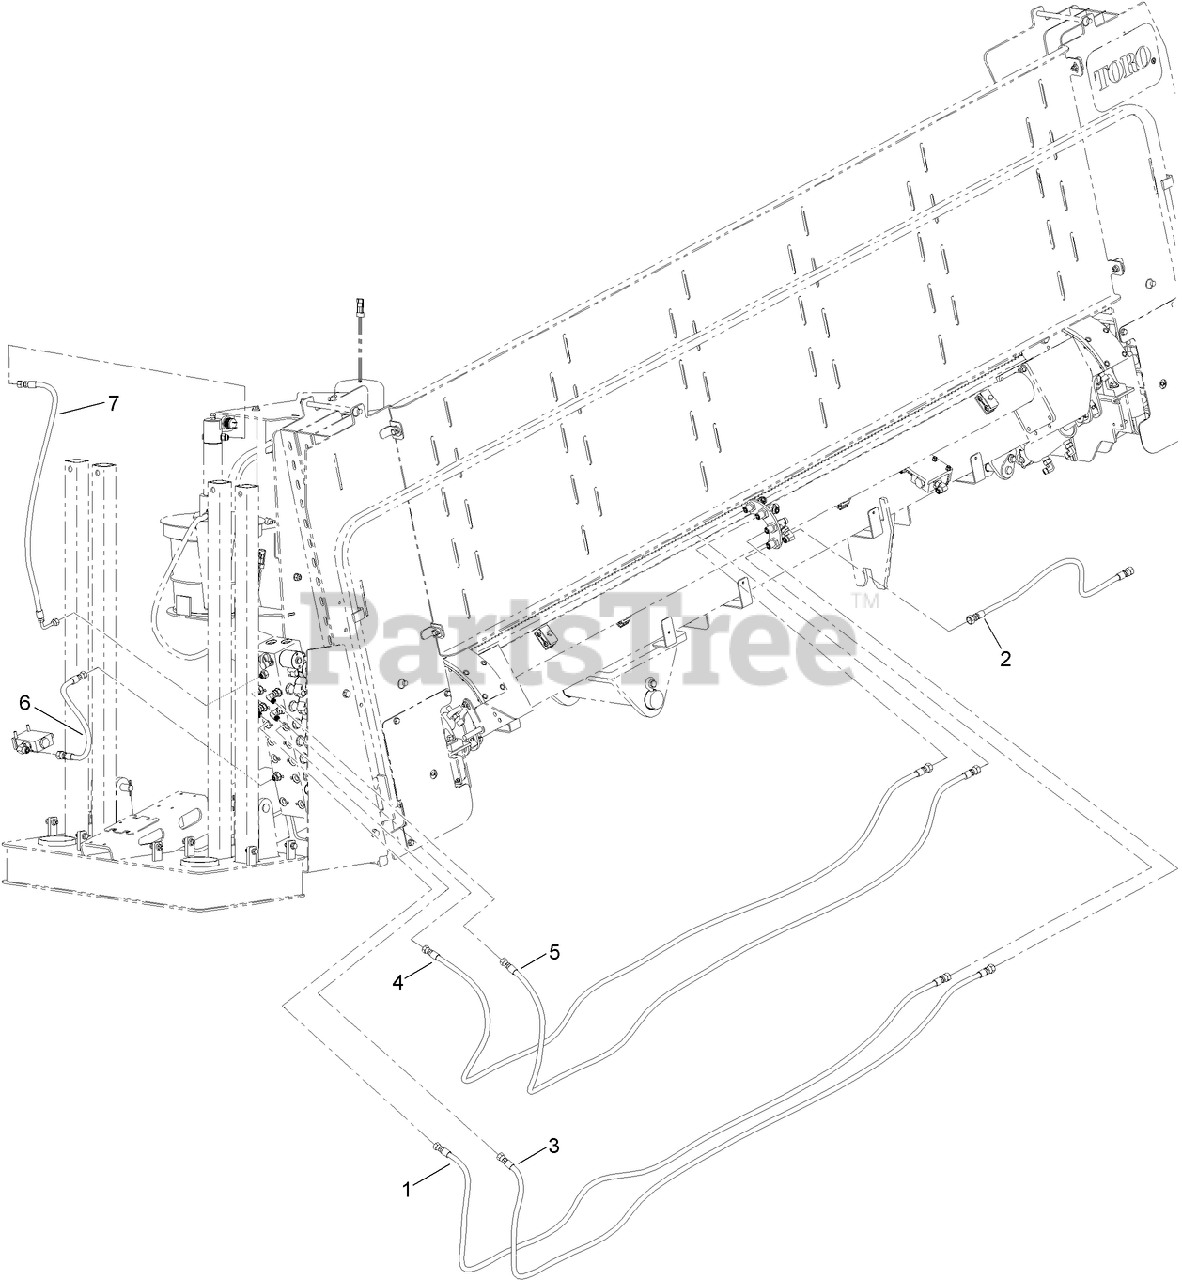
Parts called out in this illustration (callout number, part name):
1	HOSE ASM
2	HOSE ASM
3	HOSE ASM
4	HOSE ASM
5	HOSE ASM
6	HOSE ASM
7	HOSE ASM
